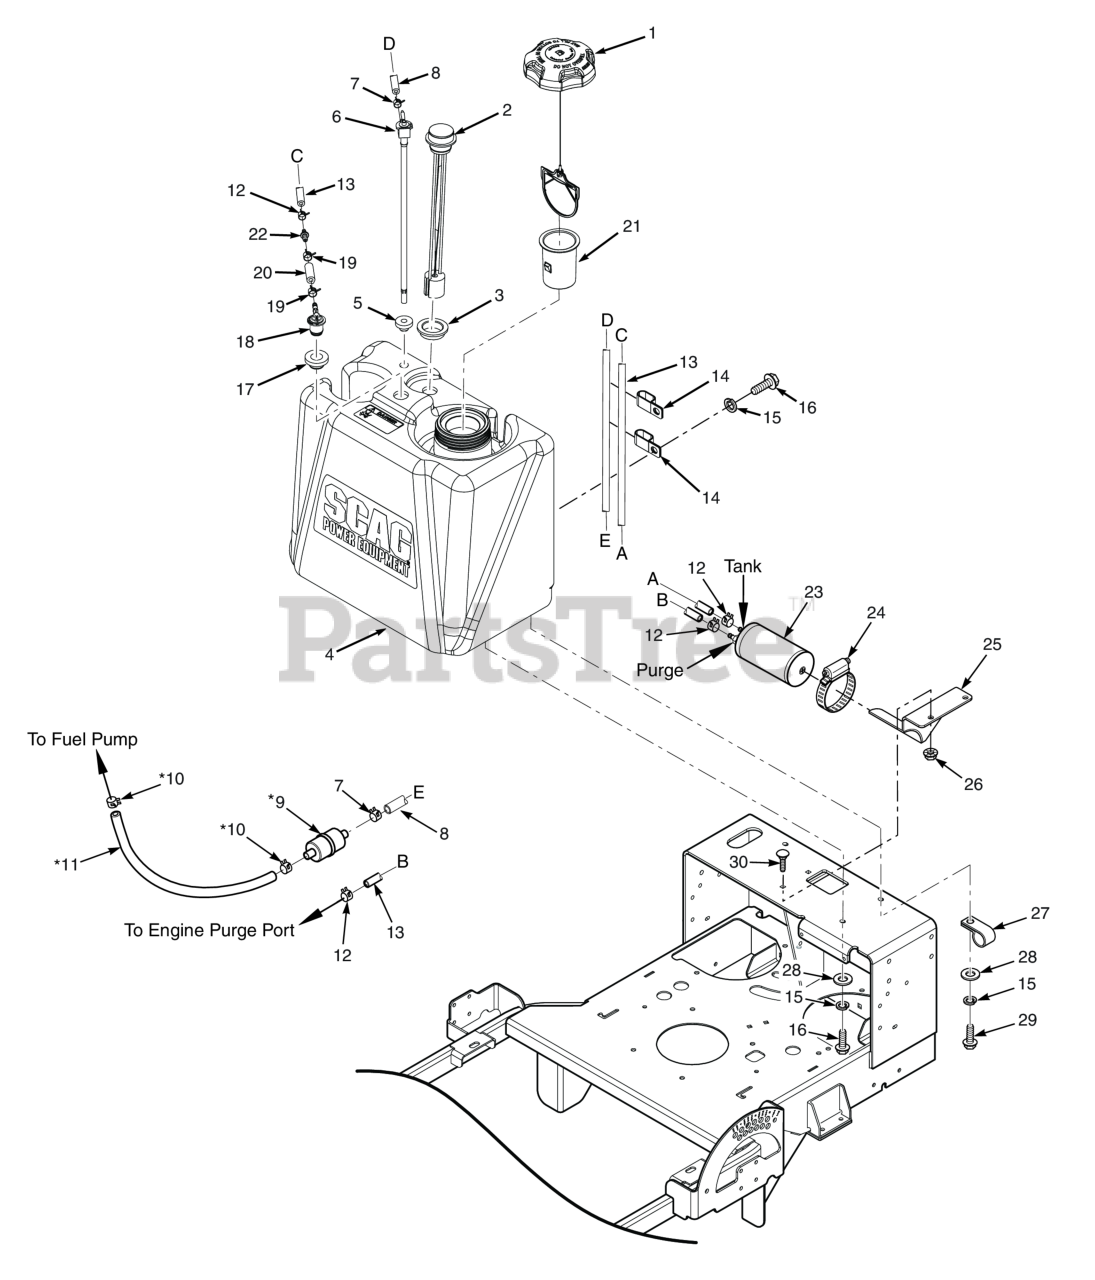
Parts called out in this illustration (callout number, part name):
1	Fuel Cap w/ Tether (E.P.A.)
2	Fuel Gauge Assembly
3	Grommet, Fuel Gauge
4	Fuel Tank Assembly (incl. #2, 3, 5, 6, 17, 18)
5	Bushing, 0.56" Dia. Viton
6	Valve, Fuel Shutoff w/Screen
7	Clamp, Fuel Hose 1/4" Hose I.D.
8	Fuel Hose, 1/4" I.D. Non-Perm (791DFI Fuel Return) - Order by Inch
9	Fuel Filter
10	Clamp, Fuel Hose
11	Fuel Hose
12	Clamp, Vapor Recovery Hose 3/16"
13	Hose, Vapor Recovery 3/16" (order by inch)
14	Clamp, Double Cable 5/8" ID.
15	Lockwasher, 5/16 (.317 x .586 x .078) Helical Spring
16	BOLT, SERRATED FLANGE HEX HEAD 5/16-18 X 3/4"
17	Grommet, Viton,
18	Remote Vent, No Valve
19	CLAMP, FUEL HOSE(KAWASAKI ONLY)
20	Hose, 1/4" Vapor Recovery (order by inch)
21	Tube, Fuel Tank Insert - 4"
22	Mender, 1/4 x 3/16 w/0.02 Hole
23	Carbon Canister - SVR-36A / SVR-48V
24	Clamp, 3-1/2" Max. Dia.
25	Bracket, Canister Mounting
26	Nut, Serrated Flange 5/16-18 (Right Front Engine Mounting, Briggs and Kohler Only)
27	Clamp, Cable 1/2" I.D.
28	Flatwasher, 5/16-.375 x .875 x .083 (35BV & 37BV-EFI)
29	Bolt, Heax Head 5/16-18 x 1" (48V / 52V)
30	Bolt, 5/16-18 x .75 RHSN Carriage
